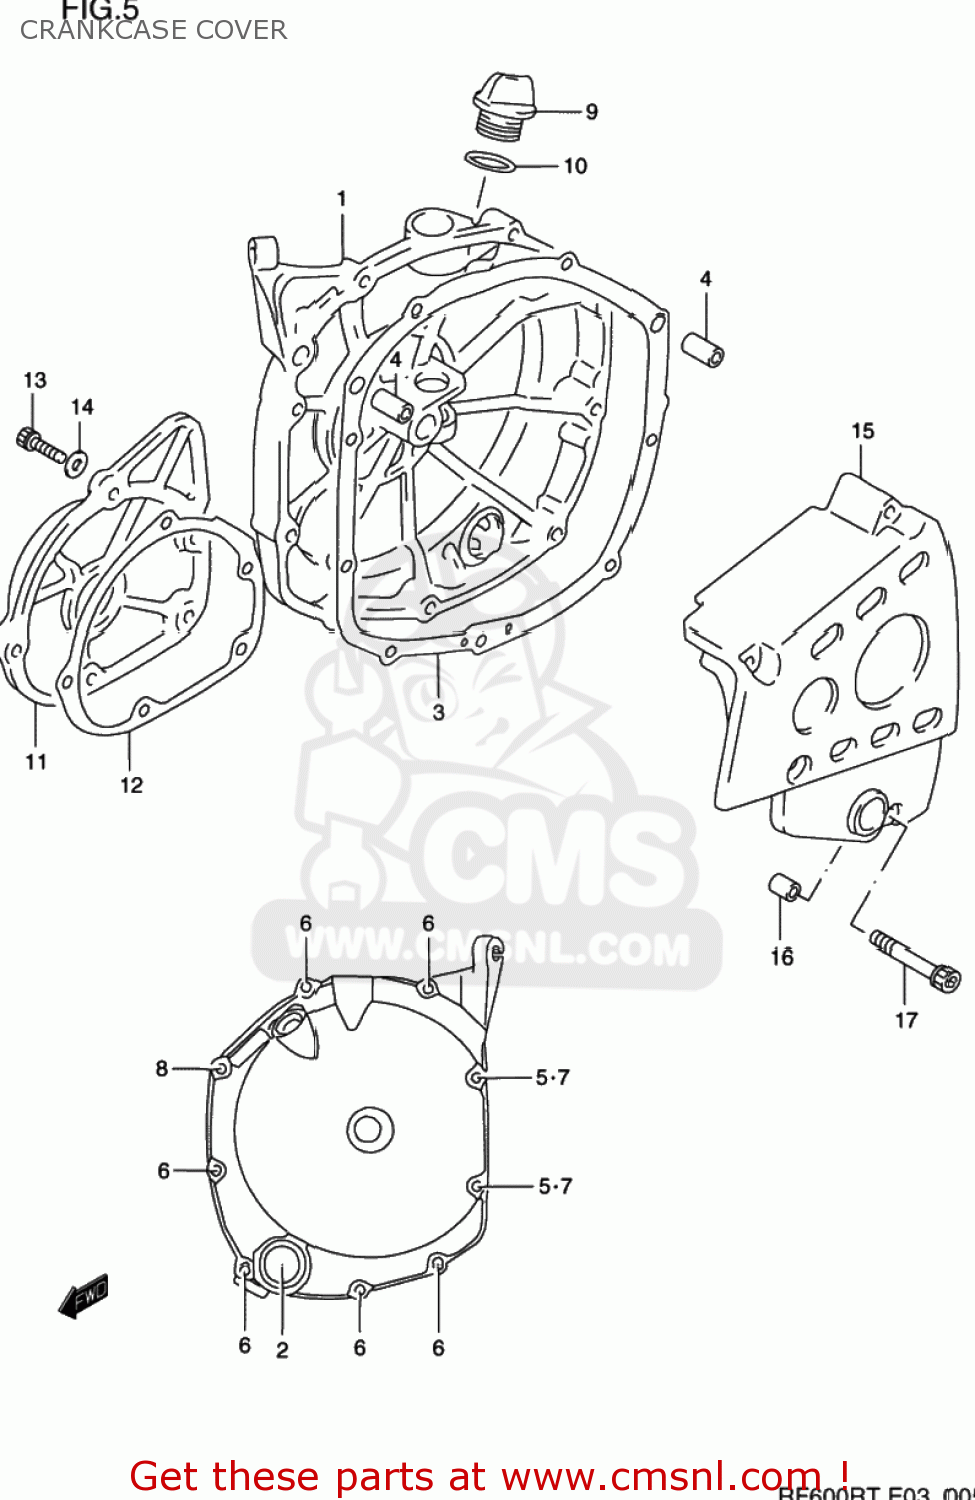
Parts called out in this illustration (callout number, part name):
1	COVER,CLUTCH
2	LENS,OIL LEVEL CHECK
3	GASKET,CL COVER (NAS)
4	PIN
5	GASKET(5.8X11X1.2) (NAS)
6	BOLT,CL.COVER
7	BOLT
8	BOLT
9	PLUG
10	O RING(D:3.1,ID:16.8)
11	COVER,SIGNAL GENERATOR
12	GASKET,SIGNAL GEN COVER
13	BOLT(6X22)
14	GASKET(5.8X11X1.2) (NAS)
15	COVER,ENGINE SPROCKET
16	PIN
17	BOLT(6X50)
